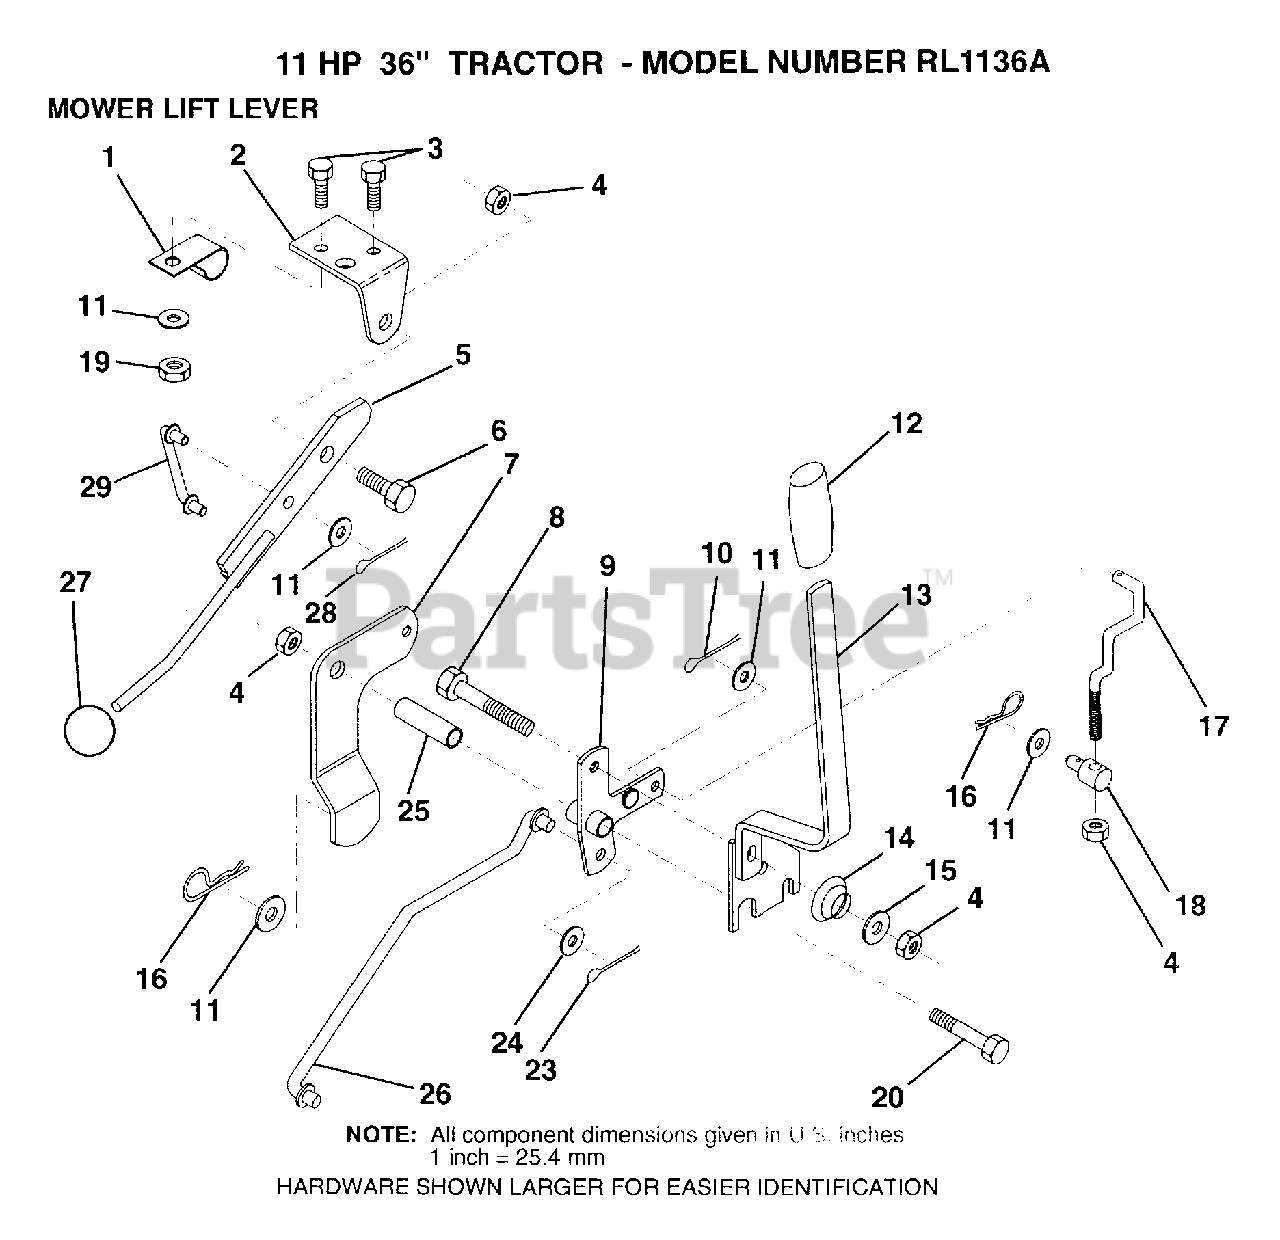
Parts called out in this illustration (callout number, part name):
1	"CLIP,INSULATOR"
2	BRKT CLUTCH
3	BOLT
5	CLUTCH LEVER AS
6	"BOLT, SHOULDER LT"
7	MWR CLUTCH ARM AS
8	BOLT
9	"BELLCRANK,LIFT"
10	COTTER PIN
11	WASHER
13	HANDLE.ASM.LIFT
14	SPRING COMPRESSIO
15	WASHER T
16	SPRING.RETAINER
17	"LINK,LIFT FRT"
18	TRUNION
20	BOLT
23	PIN COTTER 1/8
25	TUBE SPACER
26	"ROD,MOWER LIFT "
27	KNOB T(3/8 HOLE)
29	CLUTCH LINK
